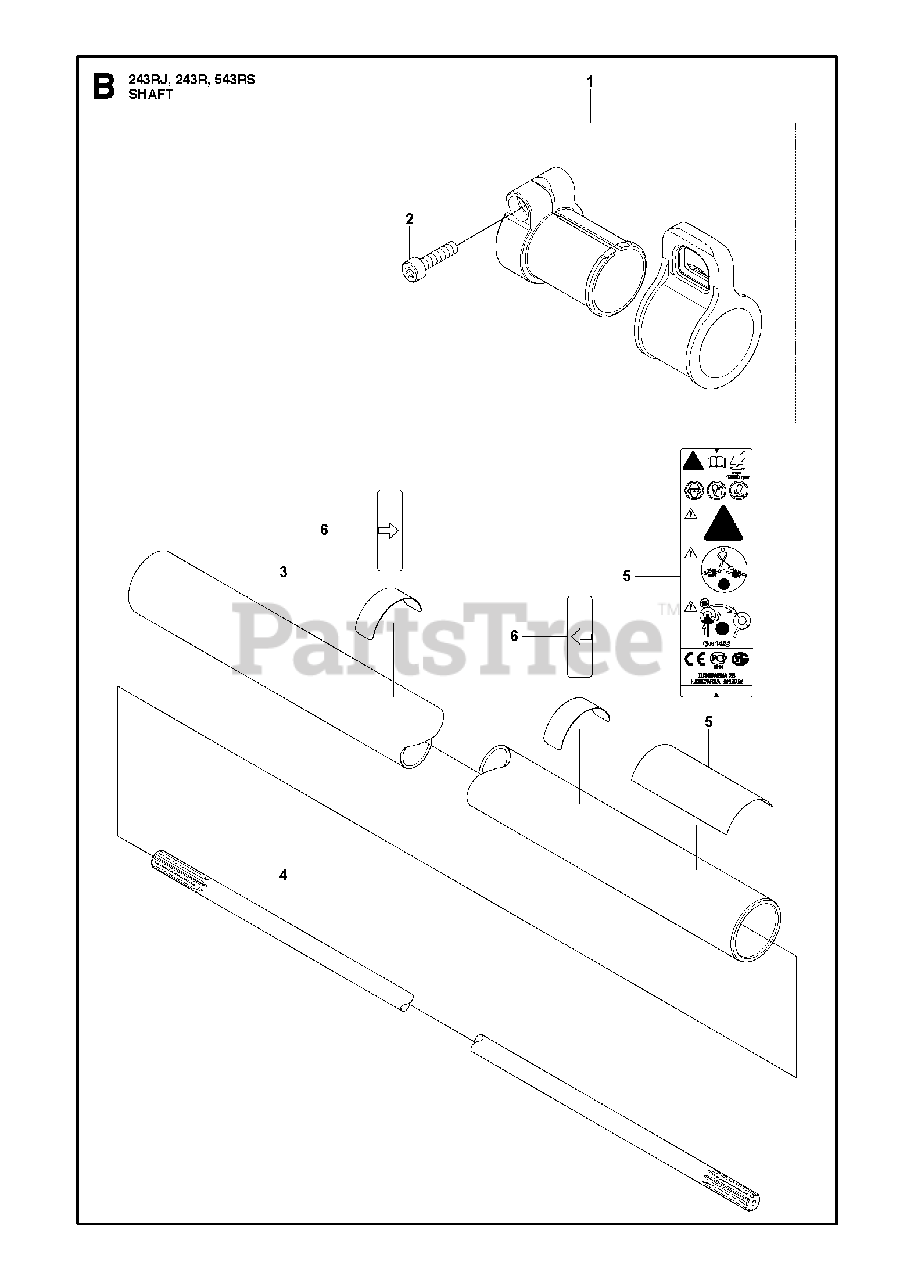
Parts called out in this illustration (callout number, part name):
1	HANGER ASSY.
2	BOLT
4	SHAFT 848JJC58E0
5	DECAL
